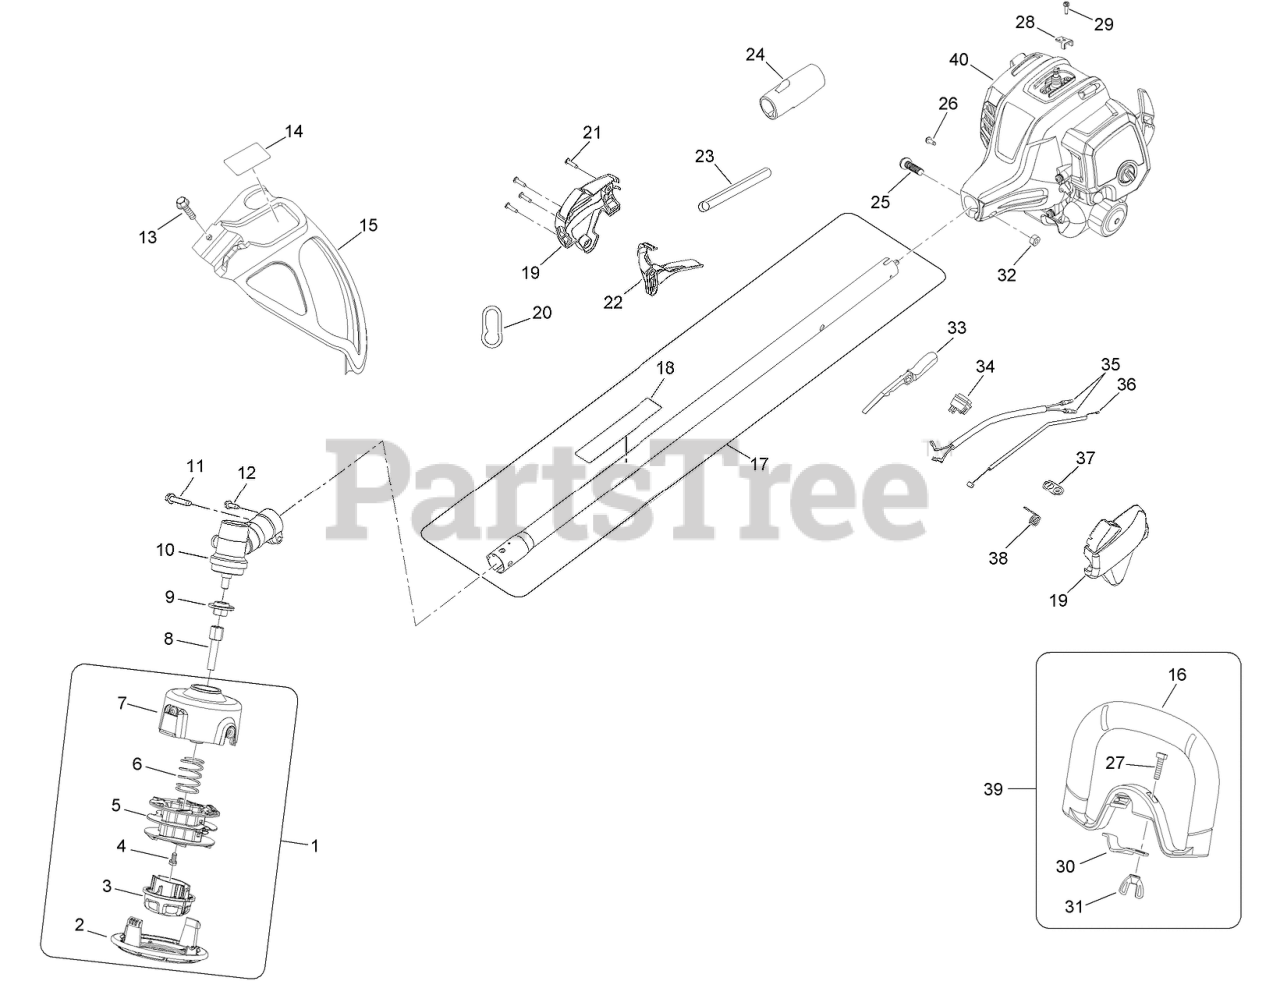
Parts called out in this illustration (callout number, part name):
2	HOUSING-STRINGHEAD, LOWER
3	KNOB-BUMP
5	SPOOL ASM
6	SPRING-COMPRESSION
8	ADAPTOR-HEAD SHAFT, TRIMMER
13	SCREW-HWH
14	LABEL-DEFLECTOR, GRASS
15	GRASS DEFLECTOR ASM
16	HANDLE-SHAFT, UPPER
17	UPPER BOOM ASM
18	DECAL-WARNING
19	CONTROL HANDLE ASM
20	CLIP-STRAP, SHOULDER
22	TRIGGER
23	TUBE-CORRUGATED
24	GRIP-SHAFT, UPPER
28	CLAMP-CABLE, THROTTLE
30	CLAMP-HANDLE, UPPER SHAFT
31	NUT-WING
32	NUT-HEX
33	LOCK-TRIGGER
34	SWITCH-ON/OFF
36	CABLE-THROTTLE
37	LABEL-ON/STOP
38	SPRING-TRIGGER
39	HANDLE ASM
40	Power Head ASM not serviced separately, for replacement parts see Power Head Components Assembly
